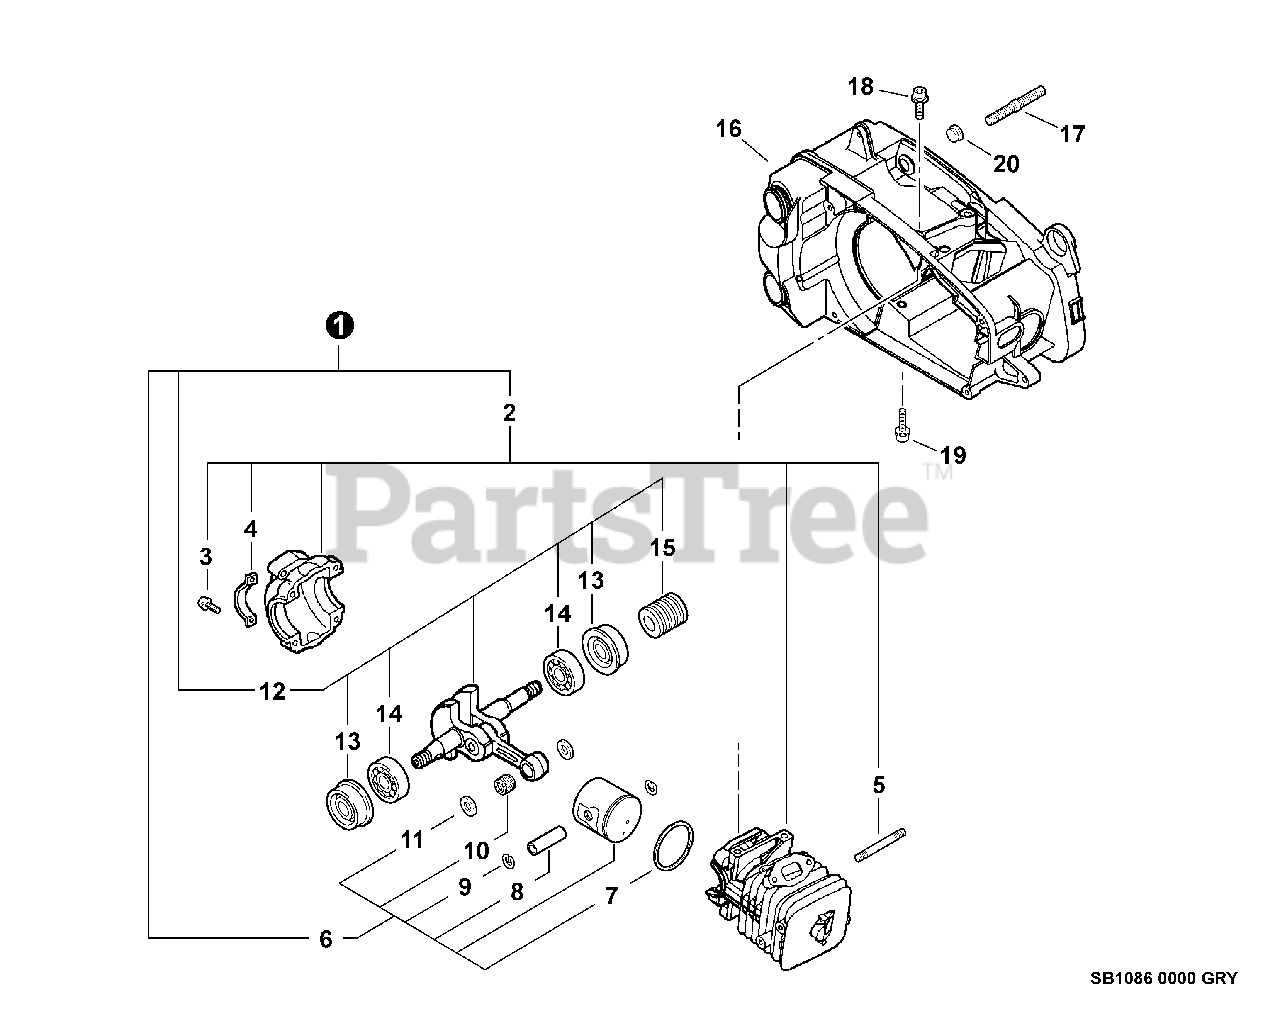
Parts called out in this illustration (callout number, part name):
1	SHORT BLOCK -- SB1086
2	CRANKCASE KIT
3	SCREW - 5X25
4	BRACKET, CRANKCASE
6	PISTON KIT
7	RING, PISTON
8	PIN, PISTON
9	RING, RETAINING
10	BEARING, NEEDLE - 8
11	SPACER, PISTON
12	CRANKSHAFT ASSY
13	SEAL, OIL - 12
14	BEARING, BALL - 6201
15	GEAR - WORM
16	COVER, ENGINE - GRAY
17	STUD, GUIDE BAR
18	SCREW - 5X20
19	SCREW - 5X30
